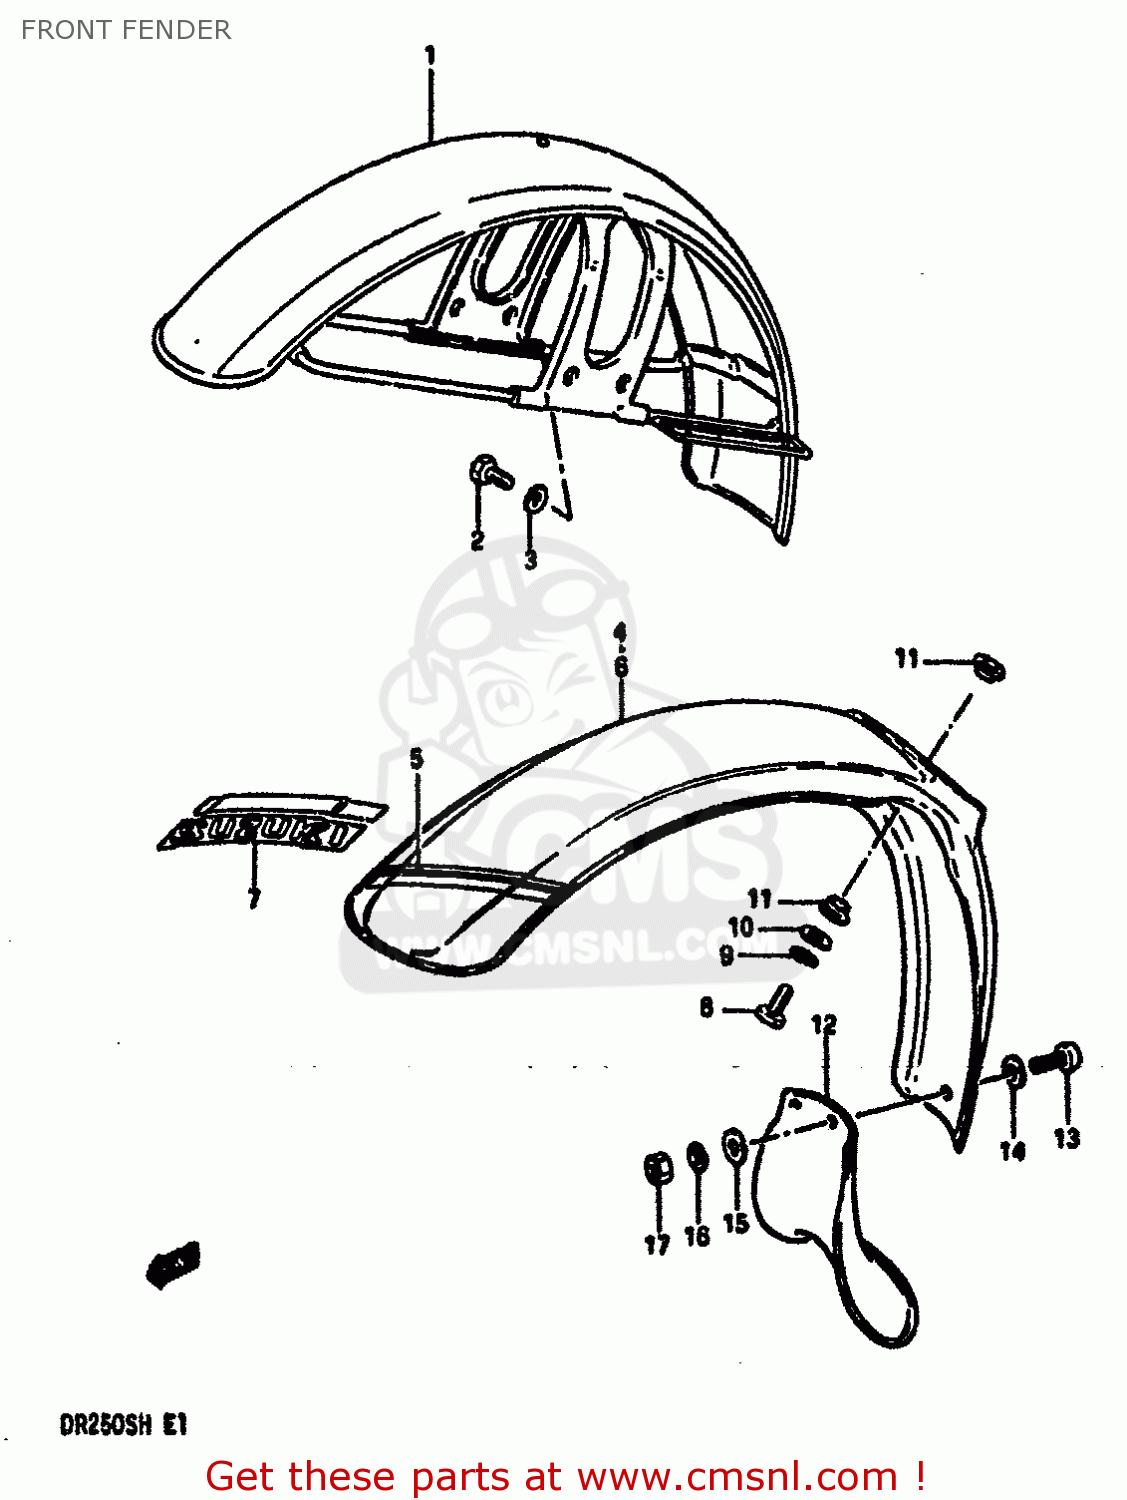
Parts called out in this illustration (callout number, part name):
1	FENDER,FR
2	BOLT,8X16
3	LOCK WASHER
4	FENDER,FRONT (BLUE)
5	TAPE SET
6	FENDER,FRONT (BLUE)
7	TAPE SET,FRONT FENDER
8	BOLT
9	WASHER,LOCK
10	WASHER
11	WASHER
12	FLAP,FR FENDER MUD
13	SCREW 6X12
14	WASHER
15	WASHER (6.7X16X1.8)
16	WASHER,LOCK
17	NUT 6MM
